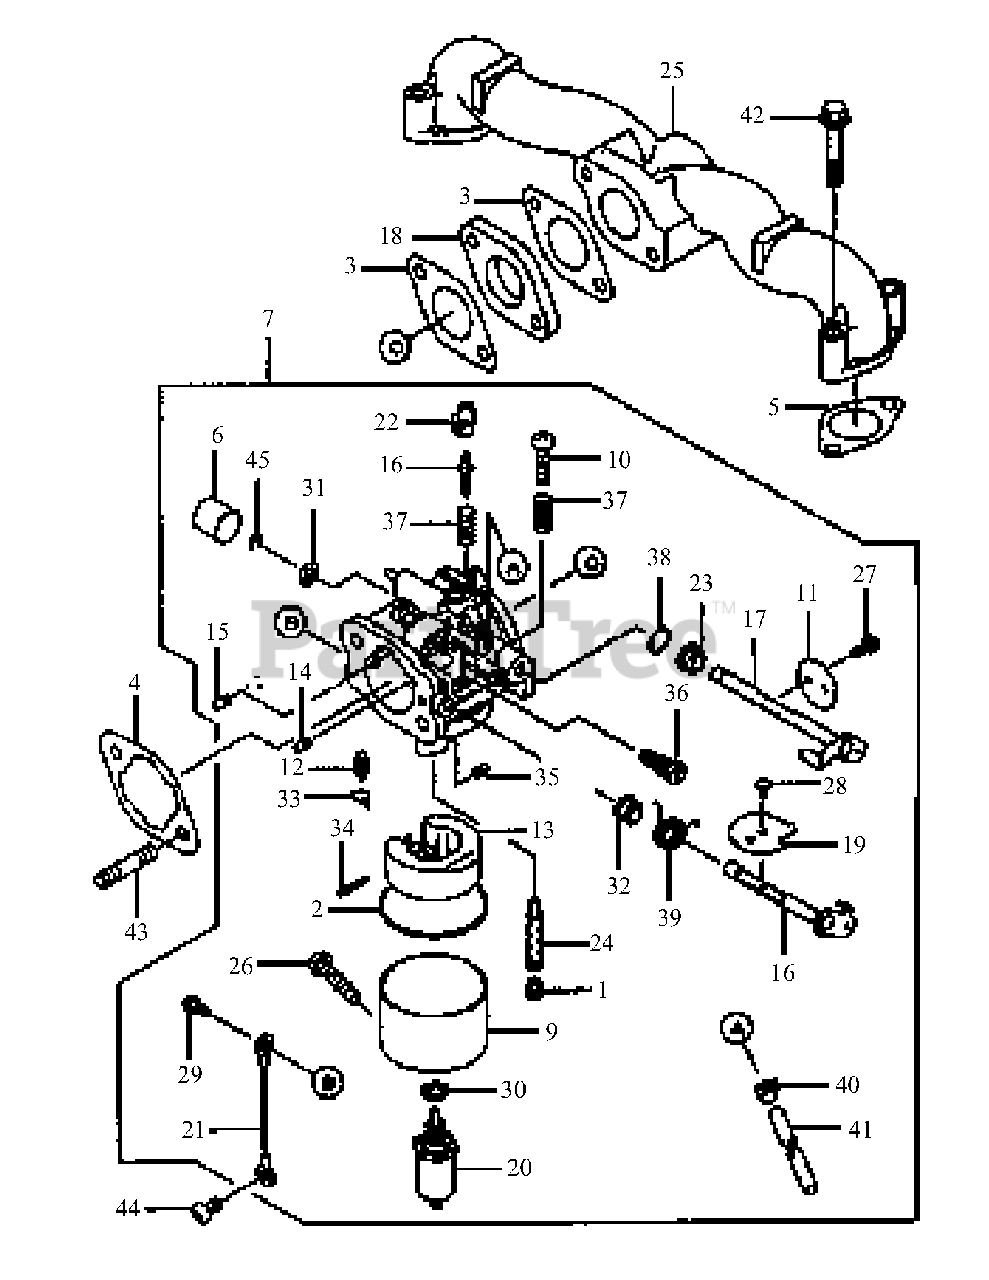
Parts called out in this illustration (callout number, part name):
3	Gasket, Insulator
4	Gasket, Air Filter
7	Carburetor Assembly
8	Screw, Pilot-Air
9	Chamber, Float
10	Screw, Throttle Stop
11	Valve, Throttle
14	Jet, Air #1.7
15	Jet, Air #1.2
17	Shart, Throttle
18	Insulator
25	Manifold, Intake
42	Bolt, Flange
45	Circlip, Type E
